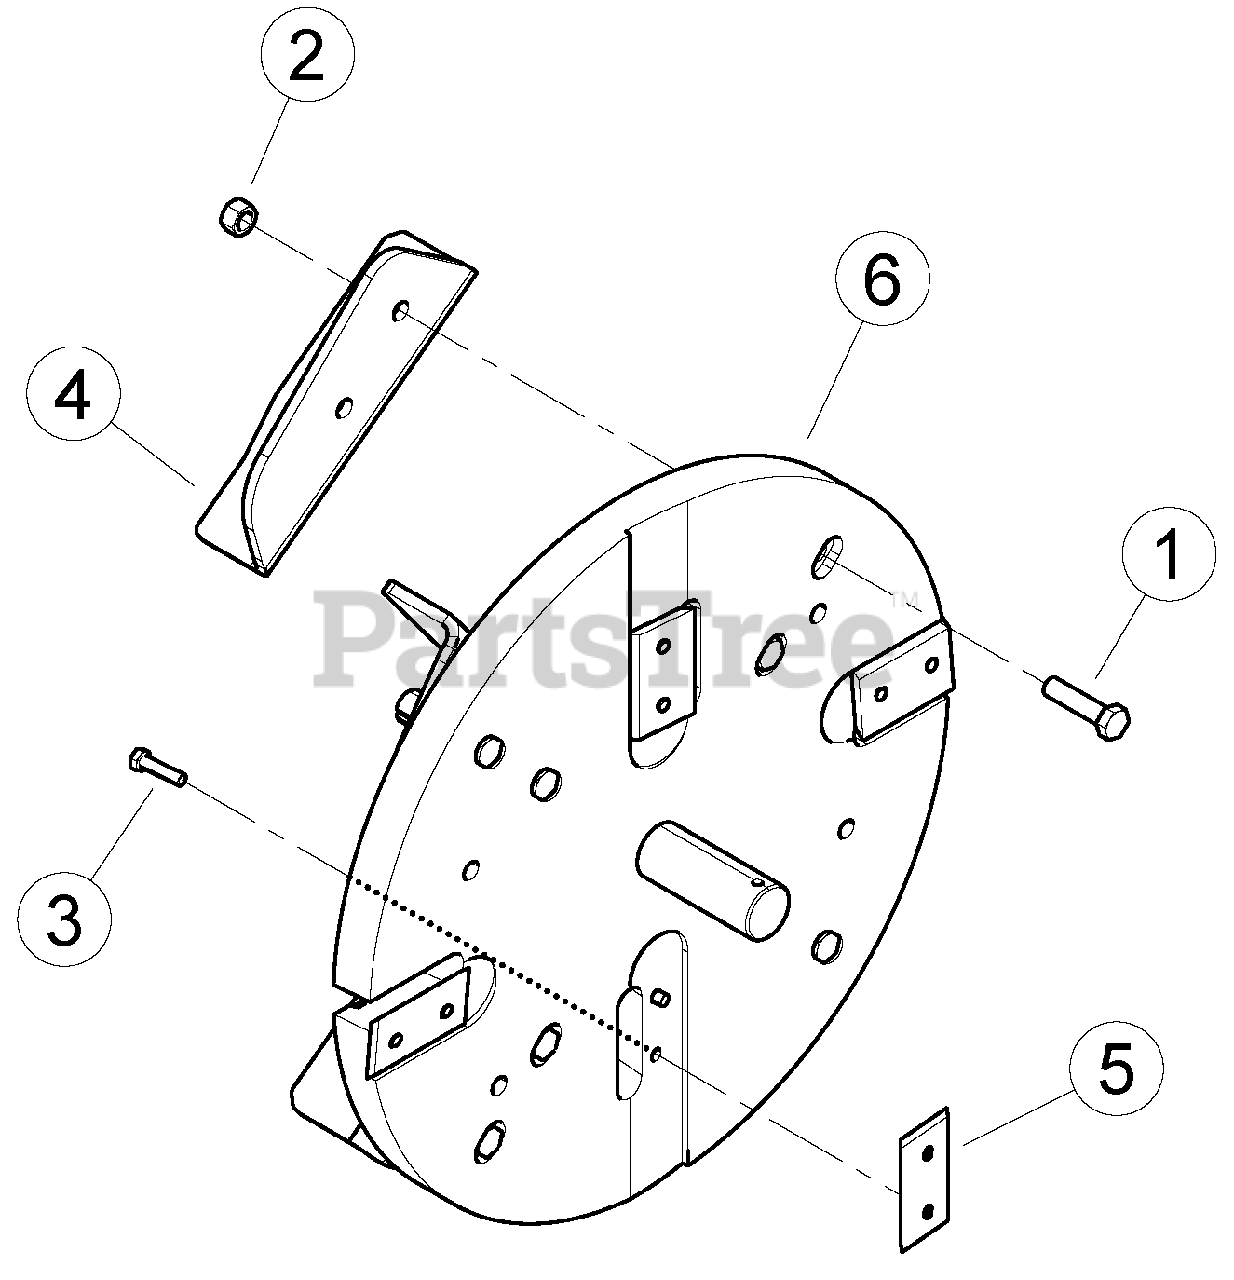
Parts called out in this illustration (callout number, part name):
1	BOLT, 1/2-13 X 2 GR5 HEX CAPSCREW
2	NUT, 1/2-13 GR5 CENTERLOCK GRB
3	BOLT, 5/16 X 1-1/4 HEX HD GR8 PATCH
4	PADDLE, 5" CHIPPER
5	KIT, CHIPPER BLADE
6	WELDMENT, ROTOR (BOBCAT)
